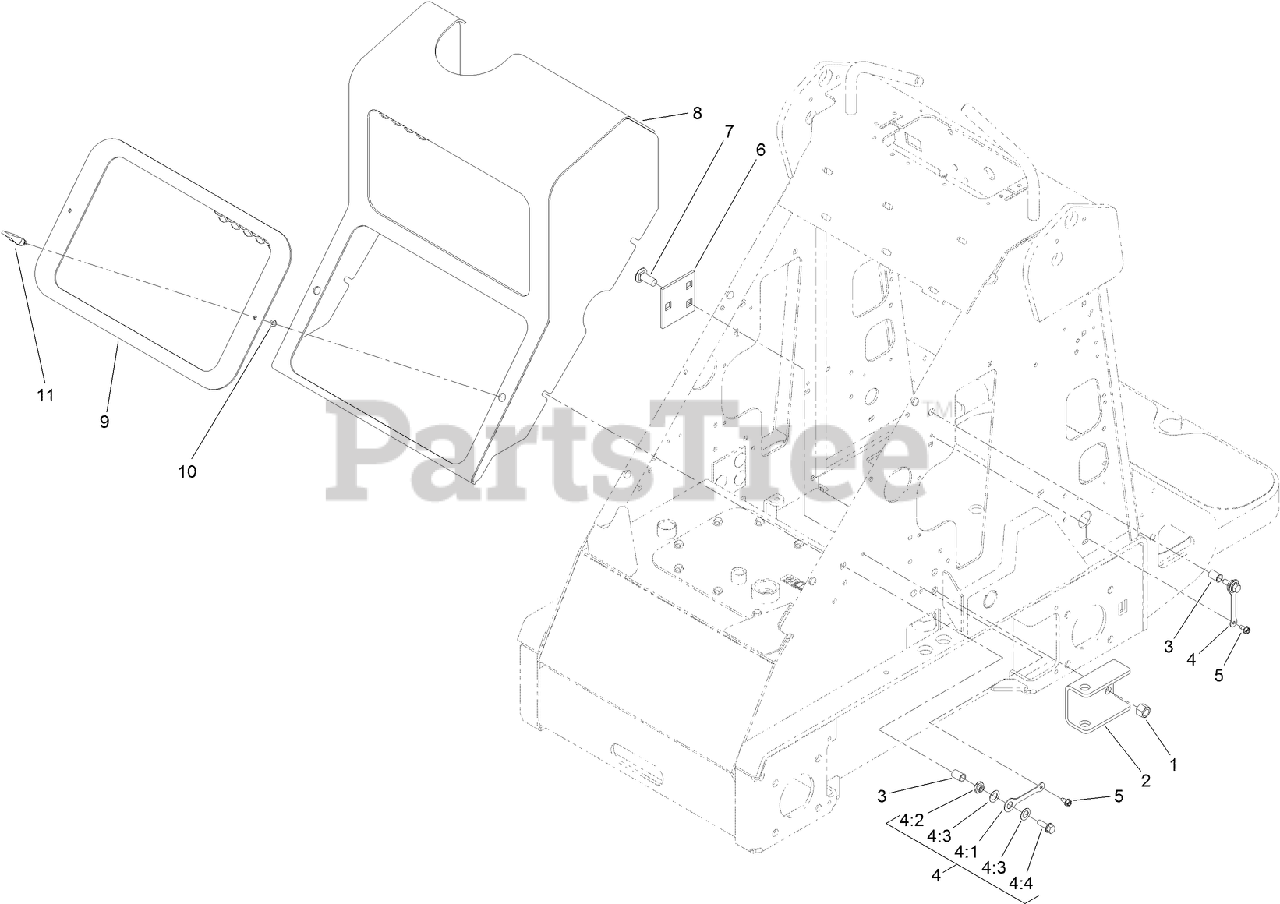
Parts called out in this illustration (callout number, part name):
1	NUT-LOCK, NI
2	BRACKET-ANCHOR
3	NUT-CLINCH
4	LANYARD ASM
4:1	LANYARD-3 INCH
4:2	NUT-SHOULDER
4:3	WASHER
4:4	SCREW-HHF
5	SCREW-HWH
6	PLATE-ANCHOR
7	SCREW-CARR, SHORT NECK
10	WASHER
11	LATCH-SWELL
